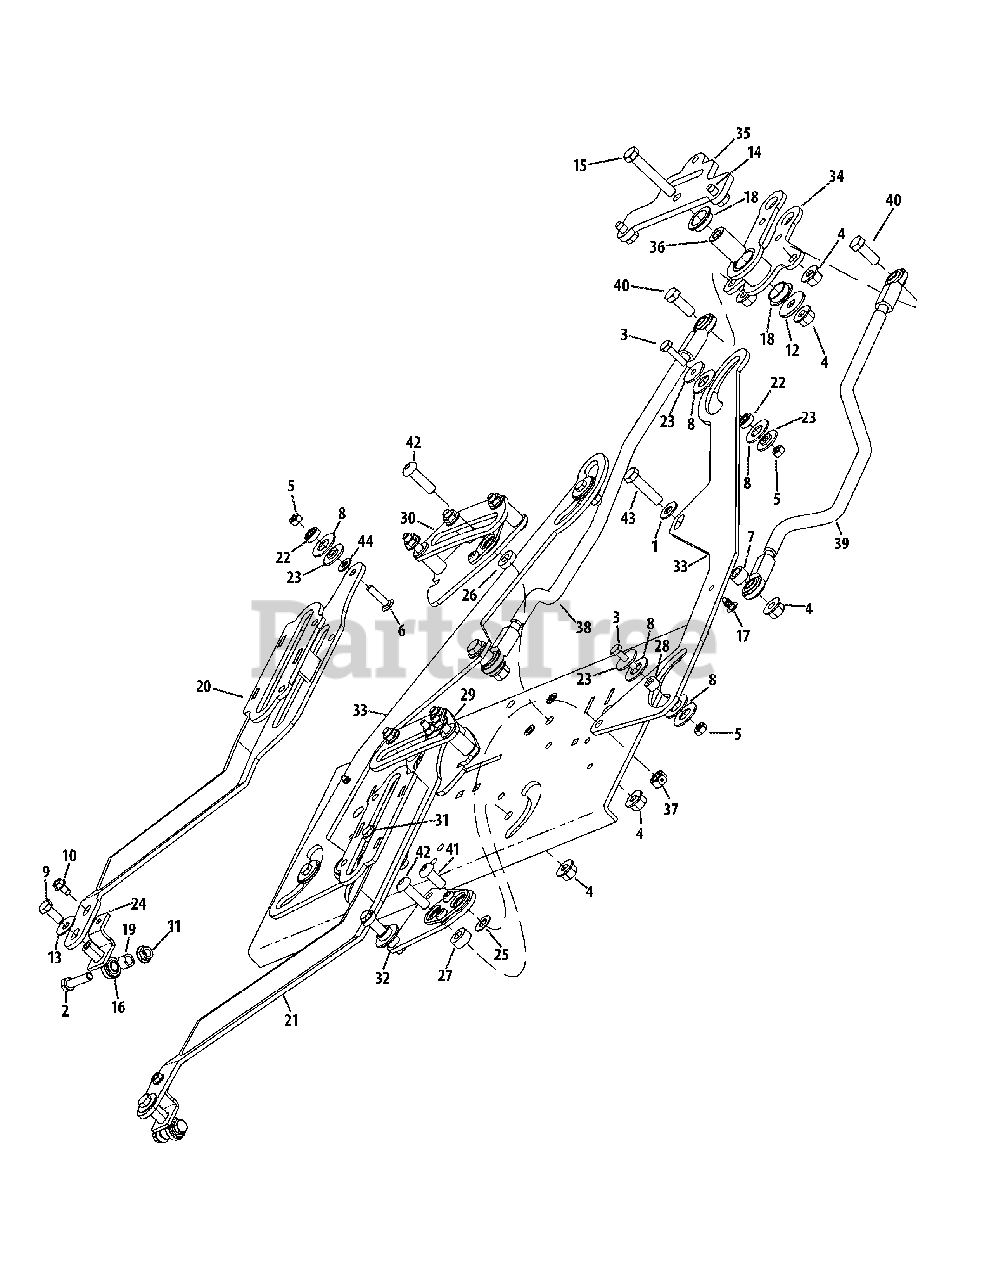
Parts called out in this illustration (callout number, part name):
1	Washer, .406 x .813 x .063
2	Hex Screw, 5/16-18 x 1.25
3	Hex Screw, 1/4-20 x 1.00
4	Flange Counter Lock Nut, 3/8-16
5	Counter Lock Nut, 1/4-20
6	Carriage Bolt, 1/4-20 x 1.00
7	Spacer, .407 x .625 x .375
8	Washer, .550 x 1.25 x .068
9	Hex Screw, 5/16-24 x .750
10	Hex Flange Screw, 1/4-20 x .500
11	Flange Counter Lock Nut, 5/16-18
12	Washer, .411 x 1.25 x 1.00
13	Bell Washer, .325 x .930 x .045
14	Flange Screw, 5/16-18 x .625
15	Hex Screw, 3/8-16 x 2.25
16	Rod End, 5/16
17	Nylon Rivet, 1/4 x .625
18	Flange Bearing, .752 x 1.25 x .305
19	Spacer, .344 x .500 x .375
20	RH Pump Control Bracket Assy.
21	LH Pump Control Bracket Assy.
22	Ball Bearing, .25 x .625 x .196
23	Shoulder Spacer, .251 x 1.00 x .06
24	Rod Support End Bracket
25	Spacer, .381 x .750 x .040
26	Spacer, .381 x .75 x .150
27	Spacer, .381 x .750 x .312
28	Spacer, .256 x .500 x .330
29	LH Speed Control Cam Assembly
30	RH Speed Control Cam Assembly
31	LH Steering Pivot Assembly
32	RH Steering Pivot Assembly
33	Control Link Plate
34	Front Steering Pivot Assembly
35	Steering Pivot Mount Plate
36	Spacer, .385 x .750 x 1.28
37	Counter Lock Nut, 3/8-16
38	LH Control Rod Assembly
39	RH Control Rod Assembly
40	Hex Screw, 3/8-16 x 1.00
41	Screw, 3/8-16 x .875
42	Screw, 3/8-16 x .1.25
43	Hex Screw, 3/8-16 x 1.50
44	Flat Washer, .25 x .630 x .0515
